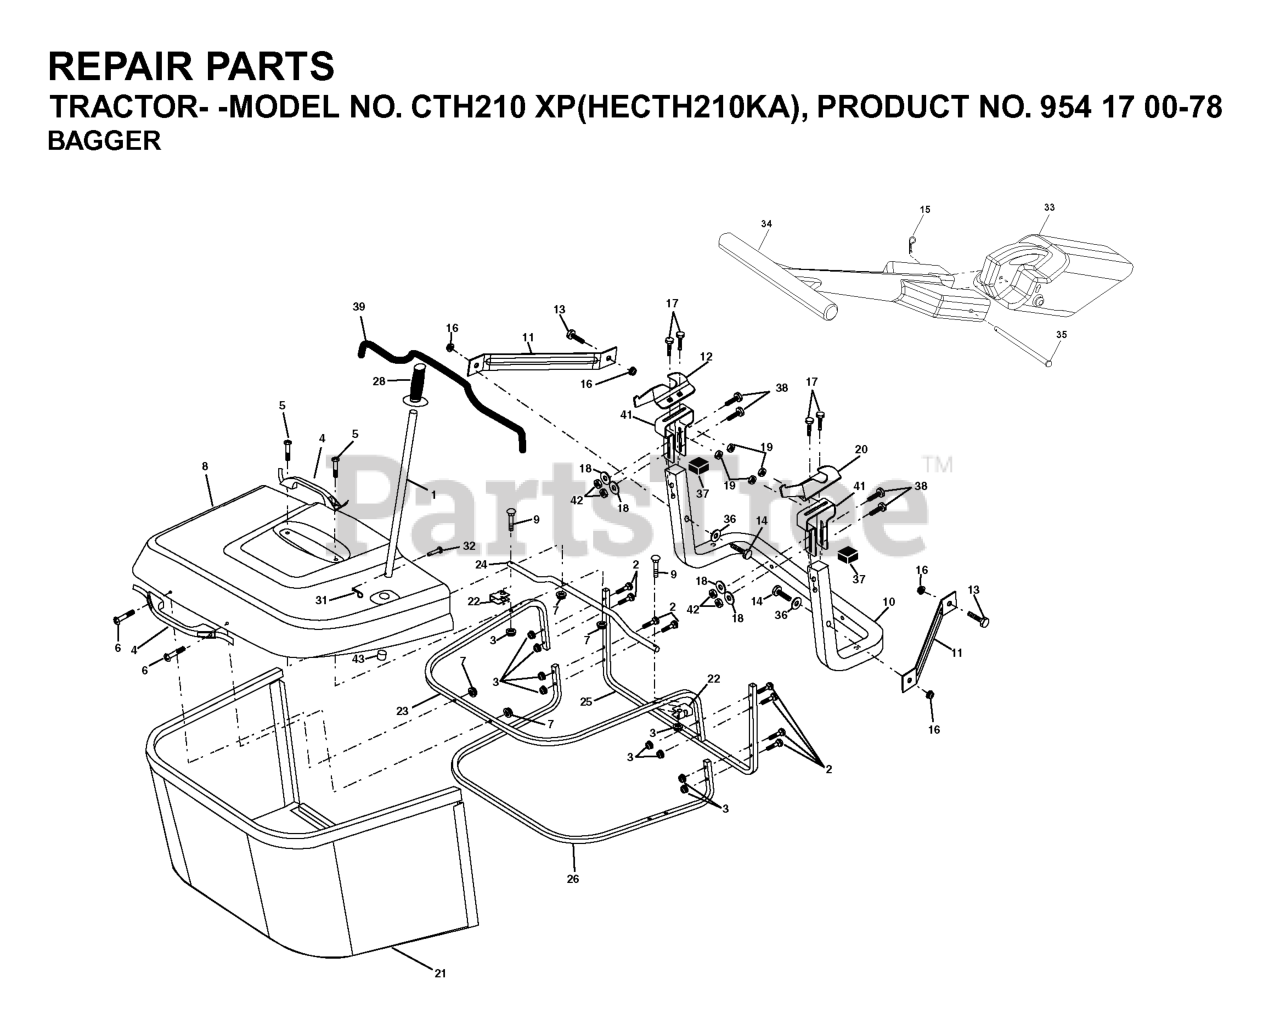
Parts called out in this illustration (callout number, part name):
1	TUBE HANDLE
2	Bolt Carriage 1/4-20 x 2.0 Gr.5
3	NUT T
4	HANDLE.BAGGER.W/LVRS.BLK.CRD
5	SCREW.PAN.HEAD
6	REPL BY 532 75 00-29
8	COVER.PNT.BGR.CRD.WSLOTS.MS668
9	Bolt Carriage 1/4-20 x 2.25d x Gr.5
10	TUBE
11	BRACKET.SUPPORT.UPPER.BAG.CRD
13	BOLT
14	BOLT-HEX EAK
15	RETAINER-SPRNG RB
16	NUT LOCK FLG 3/8-16 UNC
17	RP BOLT 5/16-18 X3/4 ZN/YEL GR
18	WASHER M
19	NUT LOCK HEX FLANGE 5/16-18
20	BRACKET
21	GRASS BAG
22	BRKT.SIDE.BAG.CRD
23	TUBE.UPPER.BAG.CRD
24	TUBE.PIVOT.BAG.CRD.BLACK
26	TUBE.LOWER.BAG.CRD
28	GRIP.HANDLE.BLACK
31	RETAINER M
32	RIVET,DRILLED
33	MULCH PLUG, CTH150
34	HANDLE.MULCHER.92.CRD (2 2)
36	WASHER
37	Plug Support Bagger CRD
38	BOLT.5/16-18X2.5
39	SEAL.TRIM.37'
41	BRKT.VERT.ADJ.BAGGER.CRD
42	NUT.71038.31-18.HEX.NYLOCK
43	PLUG, TUBING END
